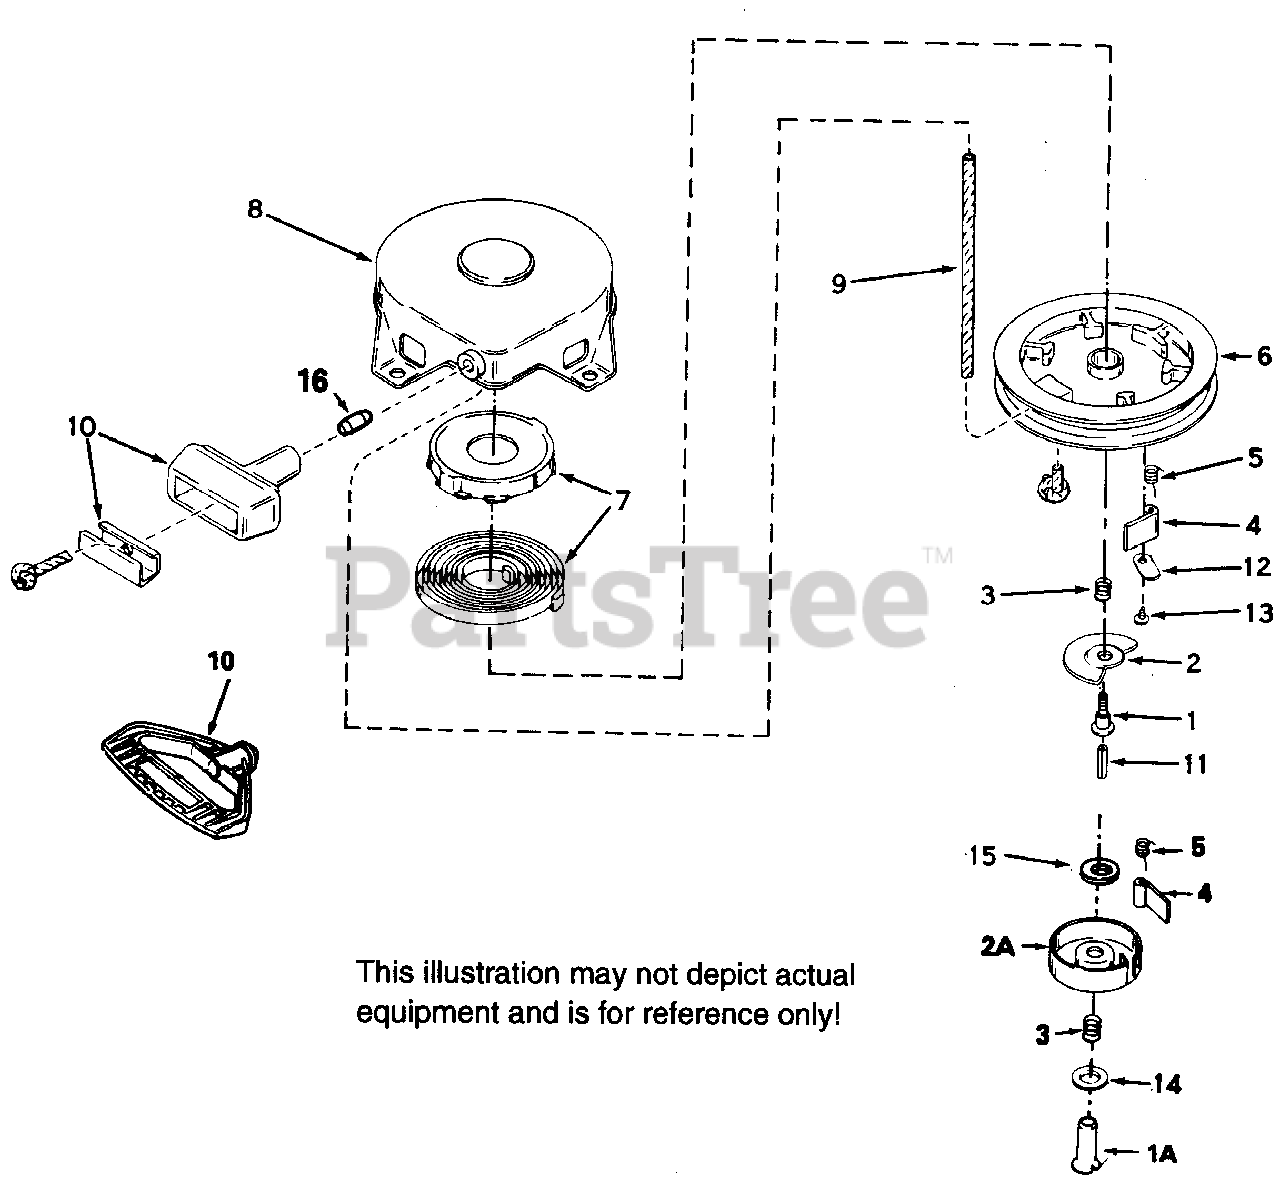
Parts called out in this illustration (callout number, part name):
1	Retainer Screw
2A	R.H. Retainer
3	Brake Spring
4	Starter Dog
5	R.H. Dog Spring
7	Spring & Keeper Ass'y.
8	Starter Housing Ass'y.
10	Starter Handle
11	Centering Pin
